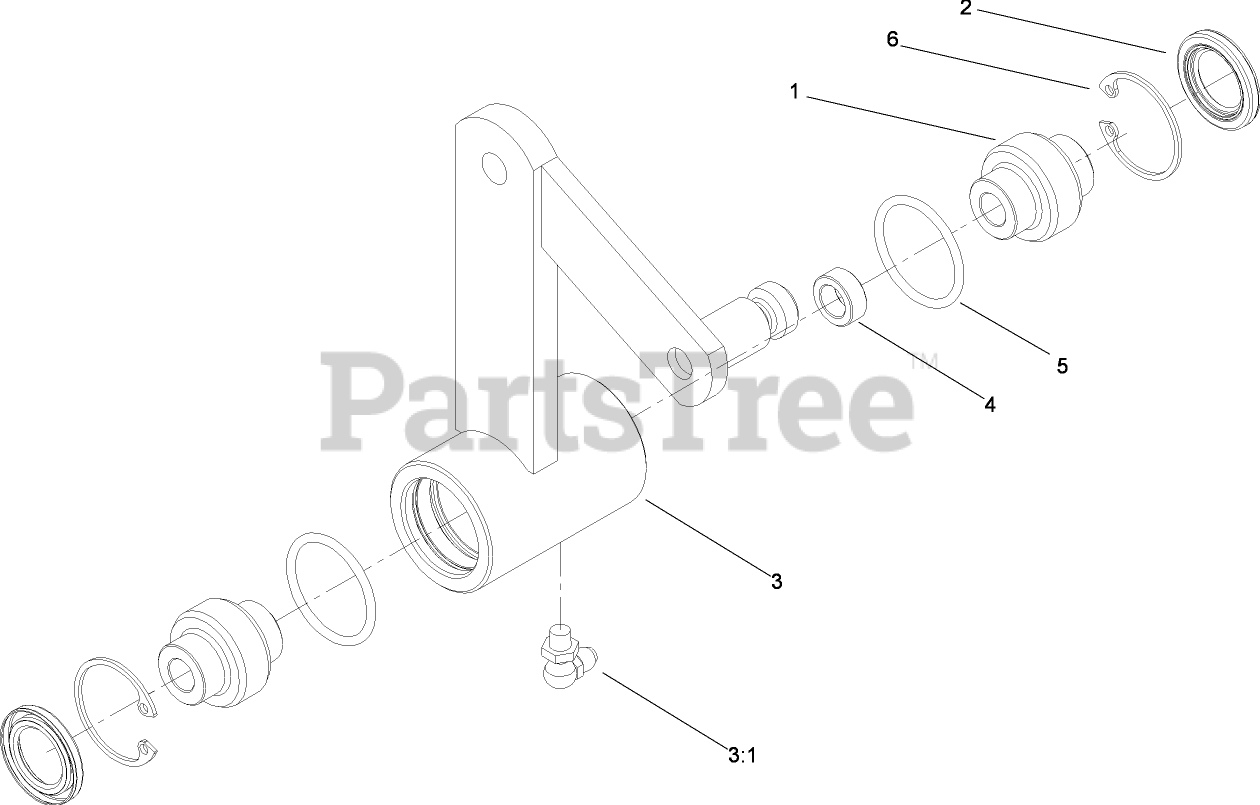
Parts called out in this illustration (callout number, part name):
1	BEARING-SPHERICAL
2	SEAL-LIP, SINGLE
3	PUMP IDLER
3:1	FITTING-GREASE, 90 DEG
4	SPACER
5	O-RING
6	RING-SNAP
